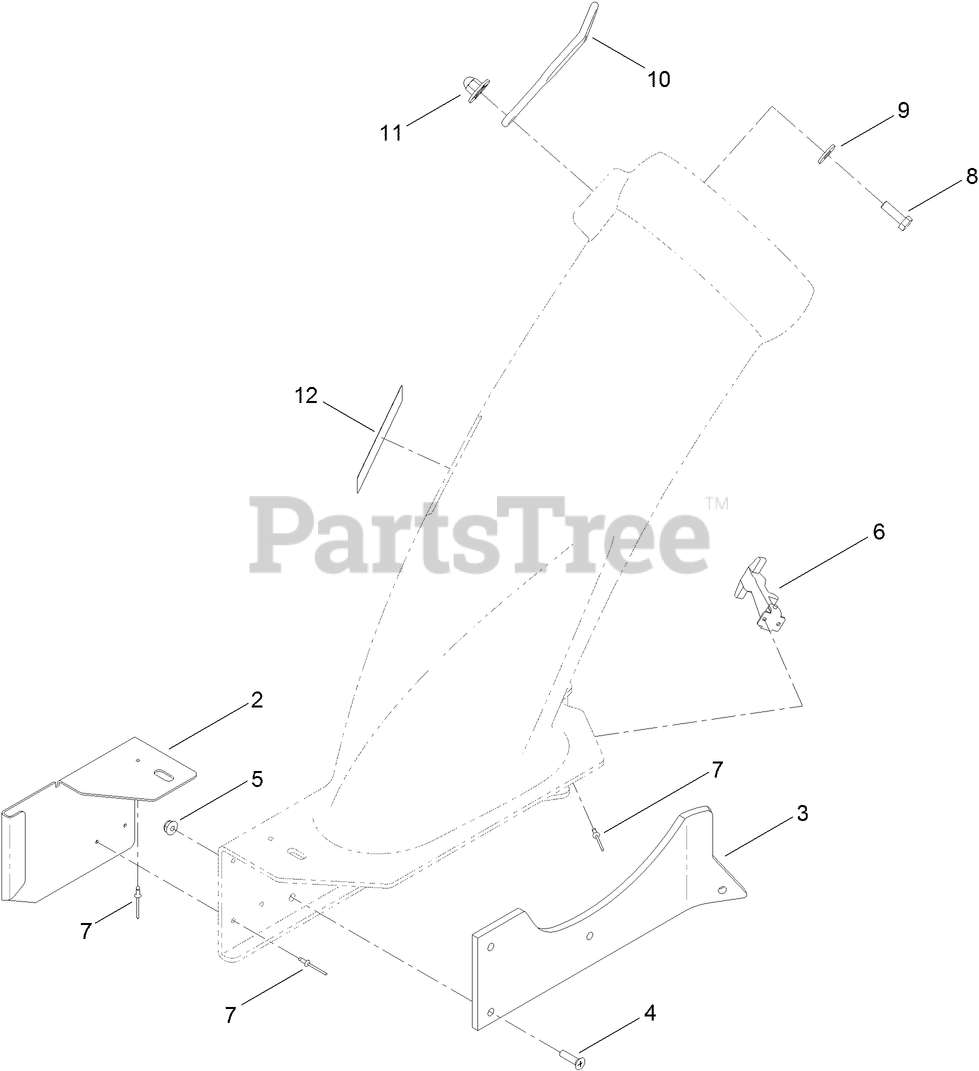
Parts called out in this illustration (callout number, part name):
2	PLATE-BAGGER
3	PLATE-SPACER
4	SCREW-FH
5	NUT-HF
6	HANDLE ASM
7	RIVET-POP
8	SCREW-HH
9	WASHER-FLAT
10	RETAINER-DUCT
11	NUT-IMPELLER
12	DECAL-DANGER
